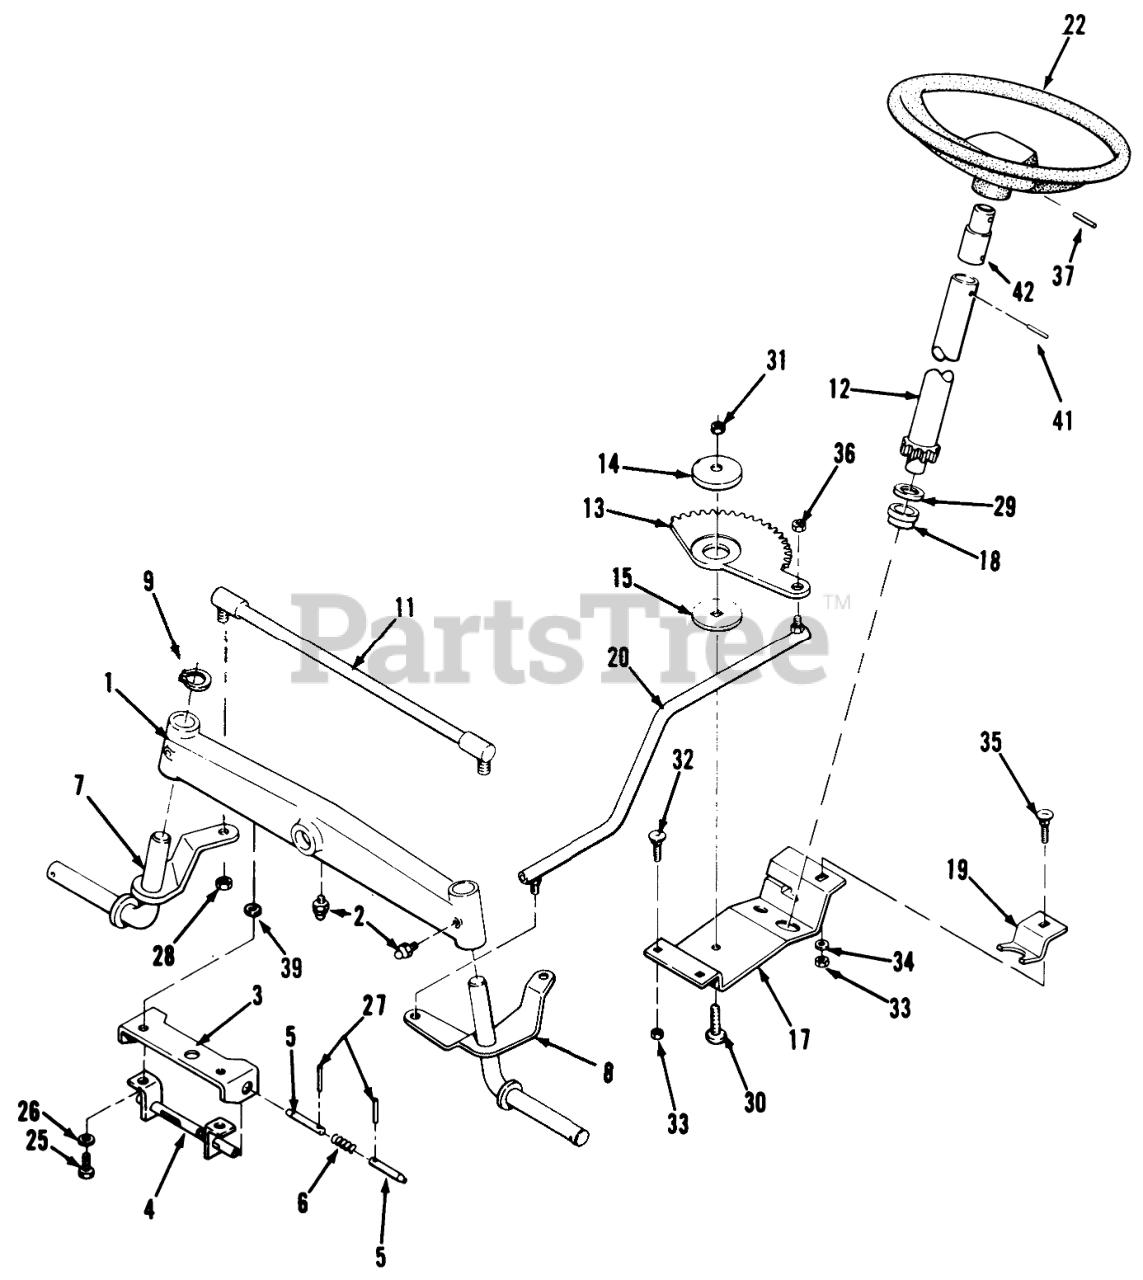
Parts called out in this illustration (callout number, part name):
1	AXLE-FRONT R
2	FITTING-GREASE
3	BRACKET-SUPPORT R
4	TUBE & BRACKET ASM R
6	SPRING
7	ASSY ARM STEERING R
8	ASSY ARM STEERING R
9	RING-RETAINING
11	ASS'Y-TIE ROD R
12	ASSY PINION & SHA B
13	GEAR SECTOR
14	BUSHING
15	WASHER-BEARING
17	BRKT-STEERING GEA R
18	BEARING-WHEEL
19	RETAINER R (NS)
20	ASSY BALL JOINT L R
22	STR'G-WHL 13" TORO
25	SCREW-HH
26	WASHER-LOCK
27	PIN-SPRING
28	Nut-Lock
29	SHIM-WASHER
30	SCREW-CARR
32	SCREW-CARR
33	SCREW-CARR
34	WASHER-PLAIN
35	BOLT-CARR
36	NUT-6
37	SPIROL PIN 5/16X13/8
39	WASHER
41	PIN-ROLL
42	SHAFT-COUPLER
